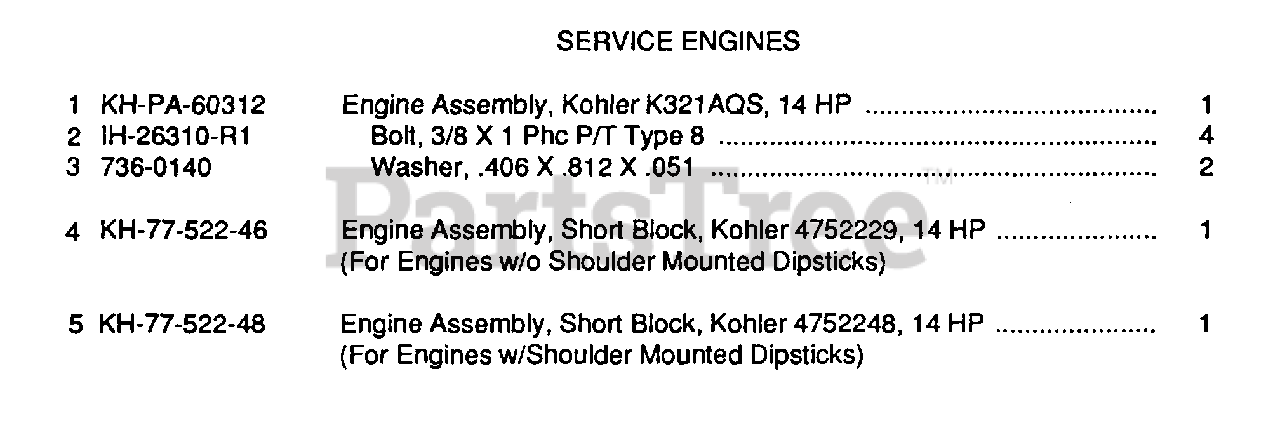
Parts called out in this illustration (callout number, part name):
1	Engine Assembly, Kohler K321AQS, 14 HP
2	Bolt, 3/8 X 1 Phc P/T Type 8
3	Washer, .406 X .812 X .051
4	Engine Assembly, Short Block, Kohler 4752229, 14 HP
5	Engine Assembly, Short Block, Kohler 4752248, 14 HP
